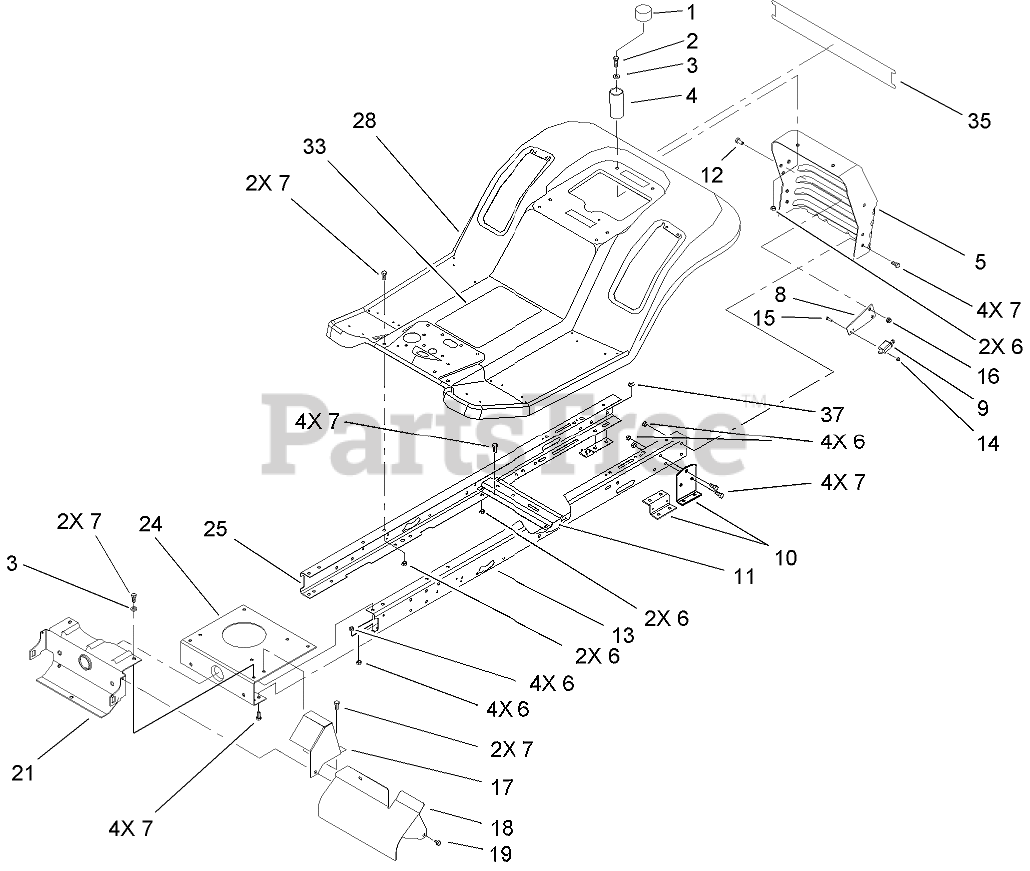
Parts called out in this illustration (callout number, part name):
1	CAP-PROTECTOR
2	SCREW-HH
3	WASHER-PLAIN
4	SPRING-COMPRESSION
5	SUPPORT-SEAT/REAR HITCH
6	NUT-LOCK, NI
7	SCREW-HH
8	PLATE-SWITCH
9	SWITCH-POLE, SINGLE
10	BRACKET-MOUNTING, TRANSMISSION
11	BRACKET-IDLER PIVOT
12	SCREW-HH
13	RAIL-FRAME, LH
14	NUT-LOCK
15	SCREW-SHH
16	NUT-LOCK, NI
17	SHIELD-EXHAUST PIPE
18	SHIELD-MUFFLER
19	SCREW-HWHTF
21	SUPPORT-FRONT, AXLE
24	PLATE-MOUNTING, ENGINE
25	RAIL-FRAME, RH
28	REAR BODY ASM
33	DECAL-INSTRUCTION
35	DECAL-REAR FENDER, LAWN TRACTORS
37	WASHER-PLAIN
